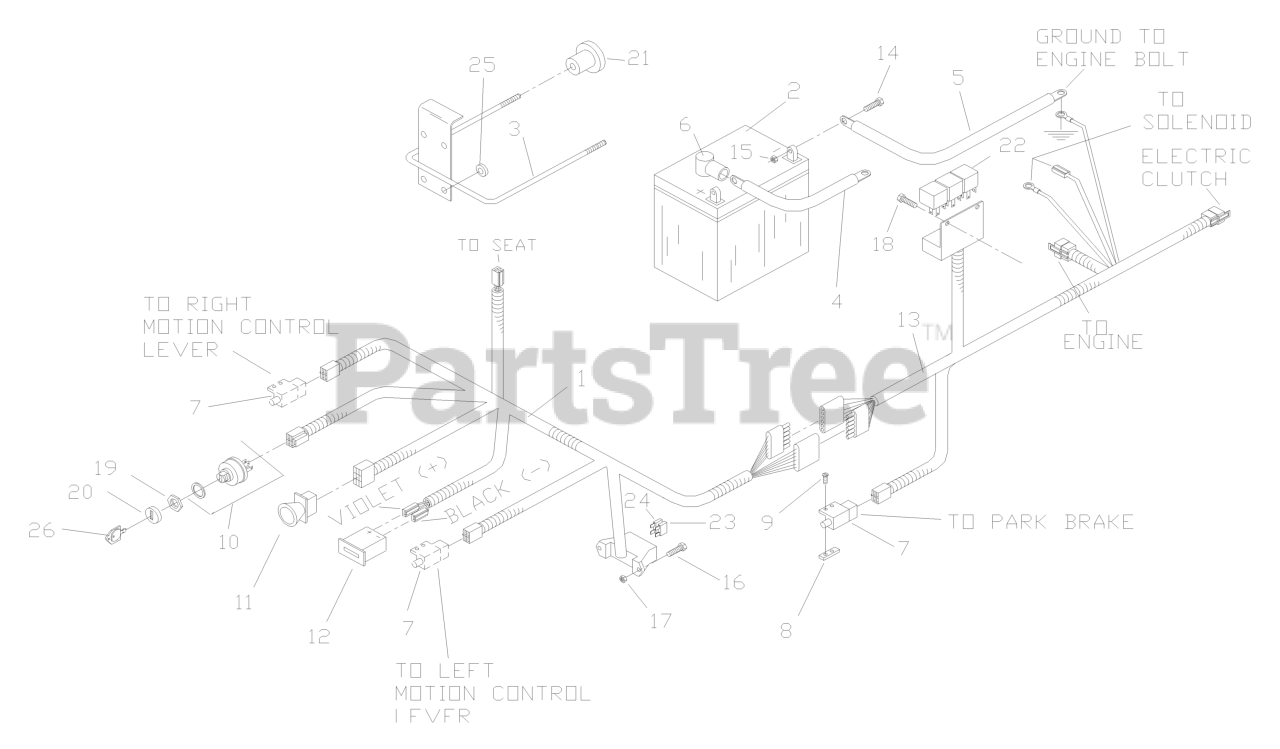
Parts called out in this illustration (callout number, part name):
1	CONSOLE HARNESS
2	BATTERY WET NOT SELLABLE
3	BATTERY HOLD DOWN
4	POST.CABLE LONG
5	CABLE-NEGATIVE
7	SWITCH, INTERLOCK
8	TAPPED PLATE
9	SCREW #10-24 X 5/8
10	IGNITION SWITCH KIT
11	RP.SWITCH, BLADE
12	HOUR METER
13	FRAMES HARNESS
14	HCS 5/16C X 3/4
15	NUT 5/16C CENTERLOCK
16	SCREW, #1--24 X 1/2 SLOTTED
17	NUT 10-24 NYLOC
18	SCREW #10 X 1/2 SELF TAPPING
19	DNO IGNITION NUT
20	CAP IGNITION NUT
23	FUSE, 7.5 AMP 32 VOLT ATO
24	FUSE, 20 AMP 32 VOLT ATO
25	GROMMET, BUMPER
26	KEY-PADDED
